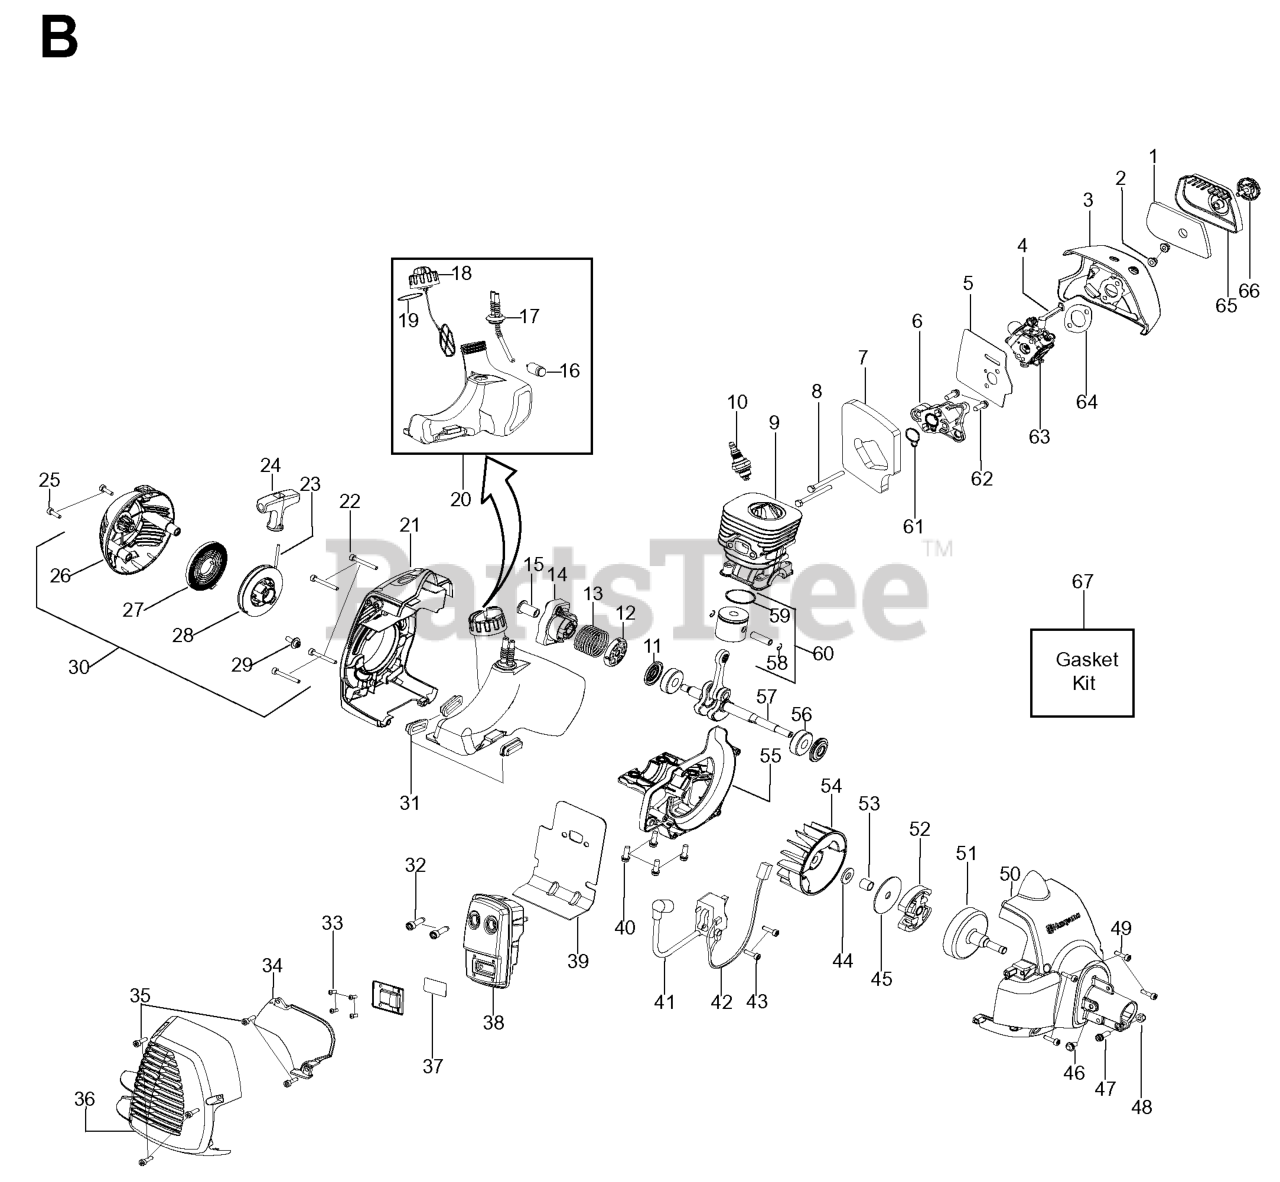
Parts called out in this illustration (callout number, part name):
1	FILTER AIRBOX
3	AIRBOX
4	CHOKE LEVER
5	KIT GASKET CARB
6	CARB ADAPTOR
7	KIT GASKET 28CC TRIMMER
8	BOLT CARB ADAPTOR
9	CYLINDER
10	Plug - Spark (RCJ-8Y)
11	KIT SEAL CRANKSHAFT
12	WASHER STARTER
13	SPRING STARTER CUP
14	ASSY STARTER CUP
15	COUPLING STARTER
16	FUEL PICK-UP ASSY
17	KIT FUEL LINE
18	ASSY-CAP W/RETAINER
19	O RING NITRILE
20	ASSY FUEL TANK
21	REAR SHROUD
24	STARTER HANDLE GRAY
25	SCREW M5-0.8X30MM
26	STARTER HOUSING
27	%KIT STARTER SPRING
28	KIT STARTER PULLEY
30	STARTER HOUSING ASSY
31	ISOLATOR FUEL TANK
32	BOLT MUFFLER
33	SCREW-10-16 X 1/2 HI-LO
34	SHIELD HEAT
35	SCREW M4 X 1.75 PT 16MM
36	MUFFLER GUARD
37	KIT SPARK ARRESTOR SCREEN
39	GASKET PAPER METAL
40	SCREW-M5-0.8 X 25MM(TAP)
41	IGNITION MODULE MBU-7
42	ASSY MODULE LEAD WIRE
43	SCREW M4 X .70 TT 16MM
45	WASHER-CLUTCH
48	NUT HEX LOCK 10-24
49	SCREW M4 X .70 TT 16MM
50	FAN HSG ASSY
51	ASSY-CLUTCH DRUM
52	%KIT CLUTCH ASSY
53	SPACER FLYWHEEL
55	CRANKCASE CASTING
56	BEARING RADIAL BALL (6201)
57	KIT CRANKSHAFT ASSY
58	WRIST PIN RET.
59	RING PISTON
60	KIT PISTON 28CC TRIMMER
61	KIT GASKET 28CC TRIMMER
62	SCREW-M5-0.8 X 25MM(TAP)
63	CARBURETOR KIT
64	KIT GASKET 28CC TRIMMER
64	COVER-AIR BOX
65	KNOB ASSY AIRBOX COVER
66	KIT GASKET 28CC TRIMMER
